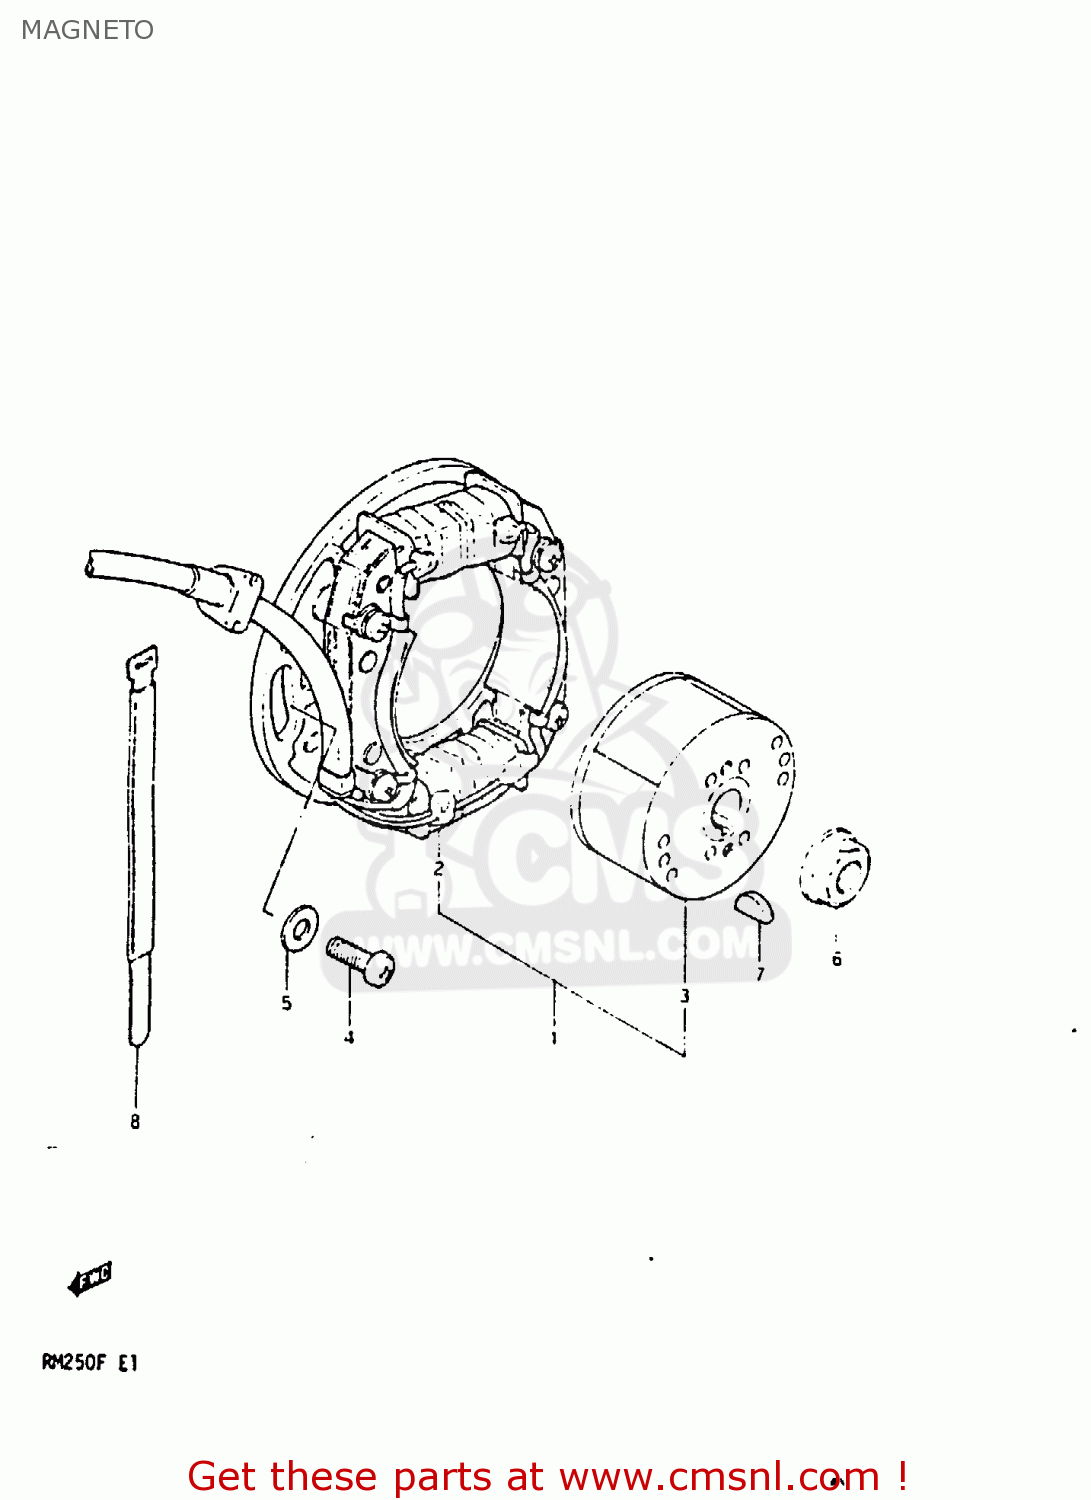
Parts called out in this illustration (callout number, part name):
1	MAGNETO ASSEMBLY
2	STATOR ASSEMBLY
3	ROTOR,FLYWHEEL
4	SCREW
5	WASHER
6	NUT
7	KEY 4MM
8	CLAMP
